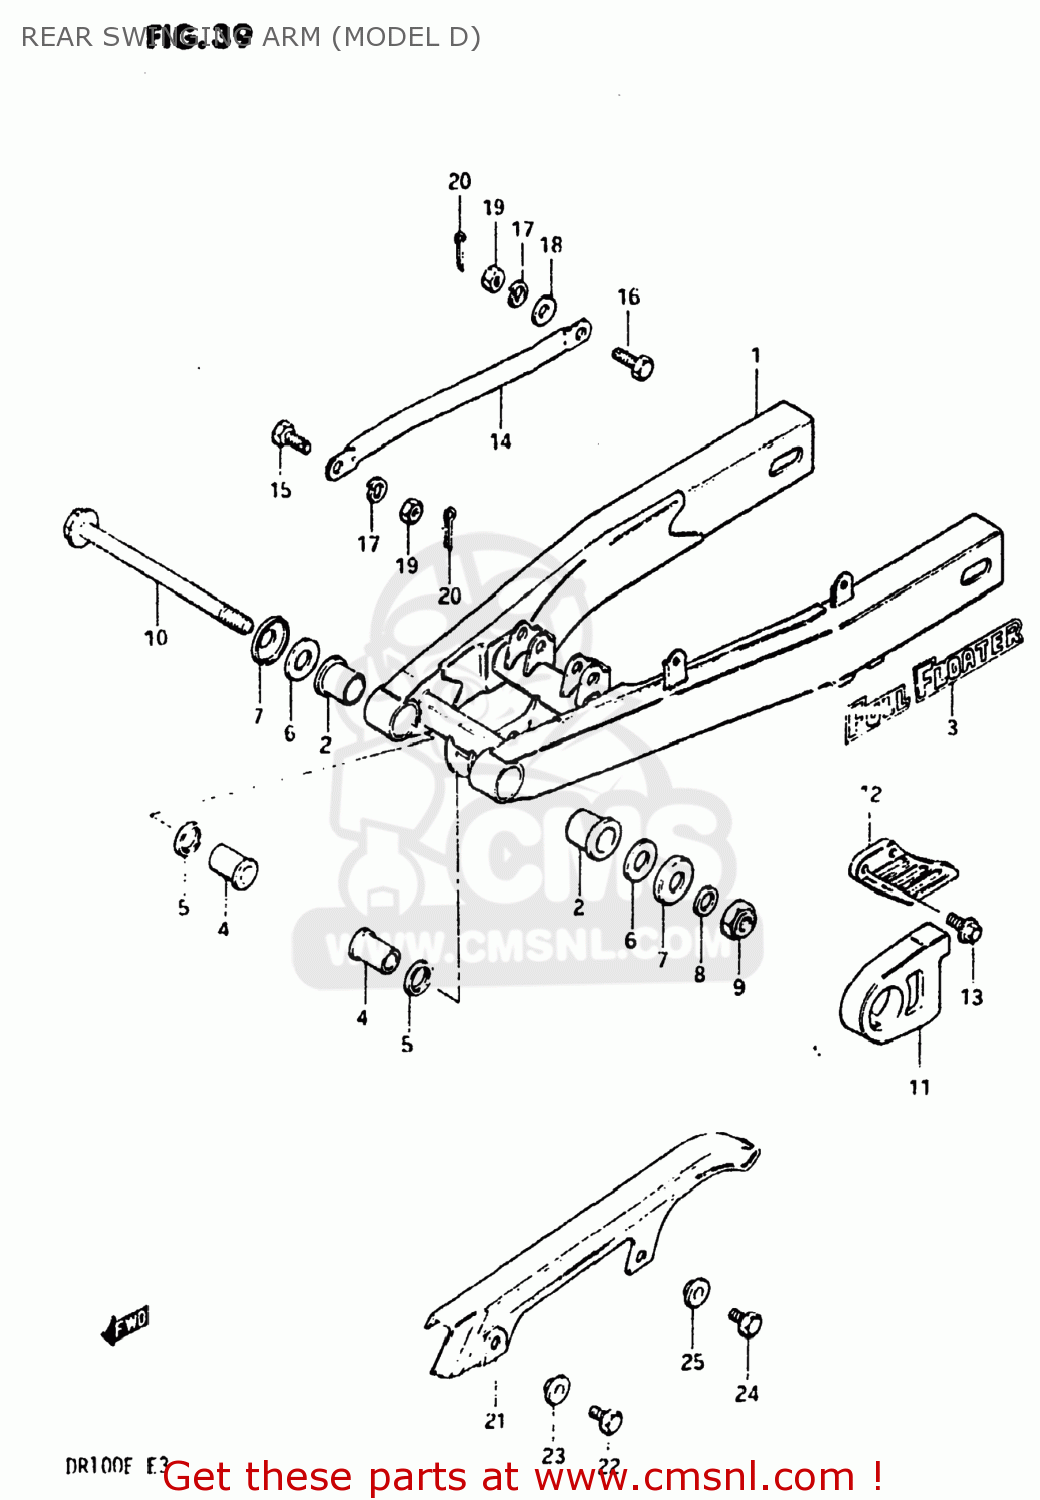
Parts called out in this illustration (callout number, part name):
1	SWING ARM ASSEMBLY,REAR
2	BUSHING,REAR SWING ARM PIVOT
3	EMBLEM,SWING ARM
4	SPACER,RR SWGARM PIVOT
5	SEAL,OIL(20X27X5)
6	WASHER
7	CVR,RR SWGARM DUST SEAL(OD:40)
8	WASHER
9	NUT 14MM
10	SHAFT,REAR SWING ARM
11	BUFFER,CHAIN TOUCH DEFLECTOR
12	GUIDE,CHAIN
13	BOLT
14	LINK,REAR TORQUE
15	BOLT(8X22)
16	BOLT(8X26.5)
17	LOCK WASHER
18	WASHER
19	NUT
20	PIN 20X20
21	CASE,CHAIN
22	BOLT 6X8
23	WASHER
24	BOLT
25	WASHER
